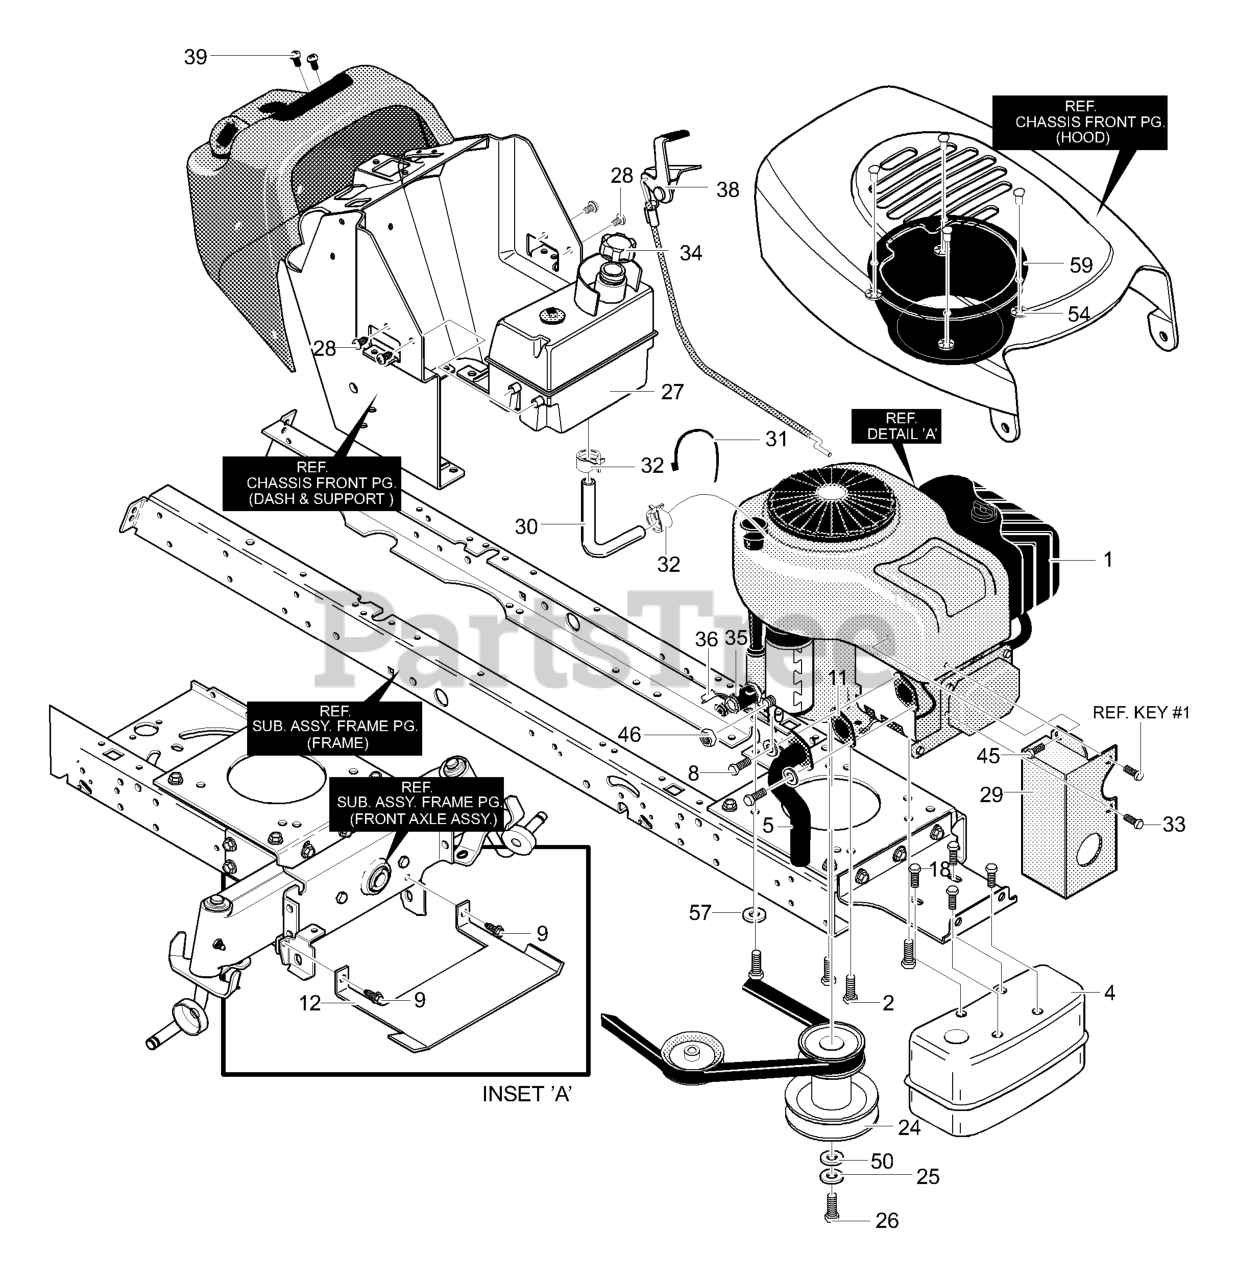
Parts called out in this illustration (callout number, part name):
2	Engine Bolt 3/8x1.25
4	Muffler
5	Exhaust Tube
8	SCREW, 5/16-18 x 0.75
9	SCREW, 5/16-18 x 0.75
10	WASHER, Regsptlk
11	Gasket, Muffler
12	SHIELD, Anti-Dehydration
18	SCREW, 1/4-20x.63
24	Stack Pulley Assembly
25	WASHER, Regsptlk
26	BOLT, 7/16-20x1.75
27	Fuel Tank w/Sensor
28	SCREW, 15TPIX
29	Heat Shield, Side
30	GAS LINE TUBING 16 In.
31	Cable Tie
32	CLAMP, Fuel Line Yellow
33	SCREW, 1/4-20x.50
34	Fuel Cap
35	Oil Drain Valve Assy.
36	Cap, Oil Drain Valve
38	Throttle Control
39	SCREW, #8-16x.50
45	SCREW, 10-16x.50
46	NUT, 1/4-20 Reghexjam
50	Flat washer
54	Pushnut
56	WASHER, Flat
57	WASHER, Exlk
